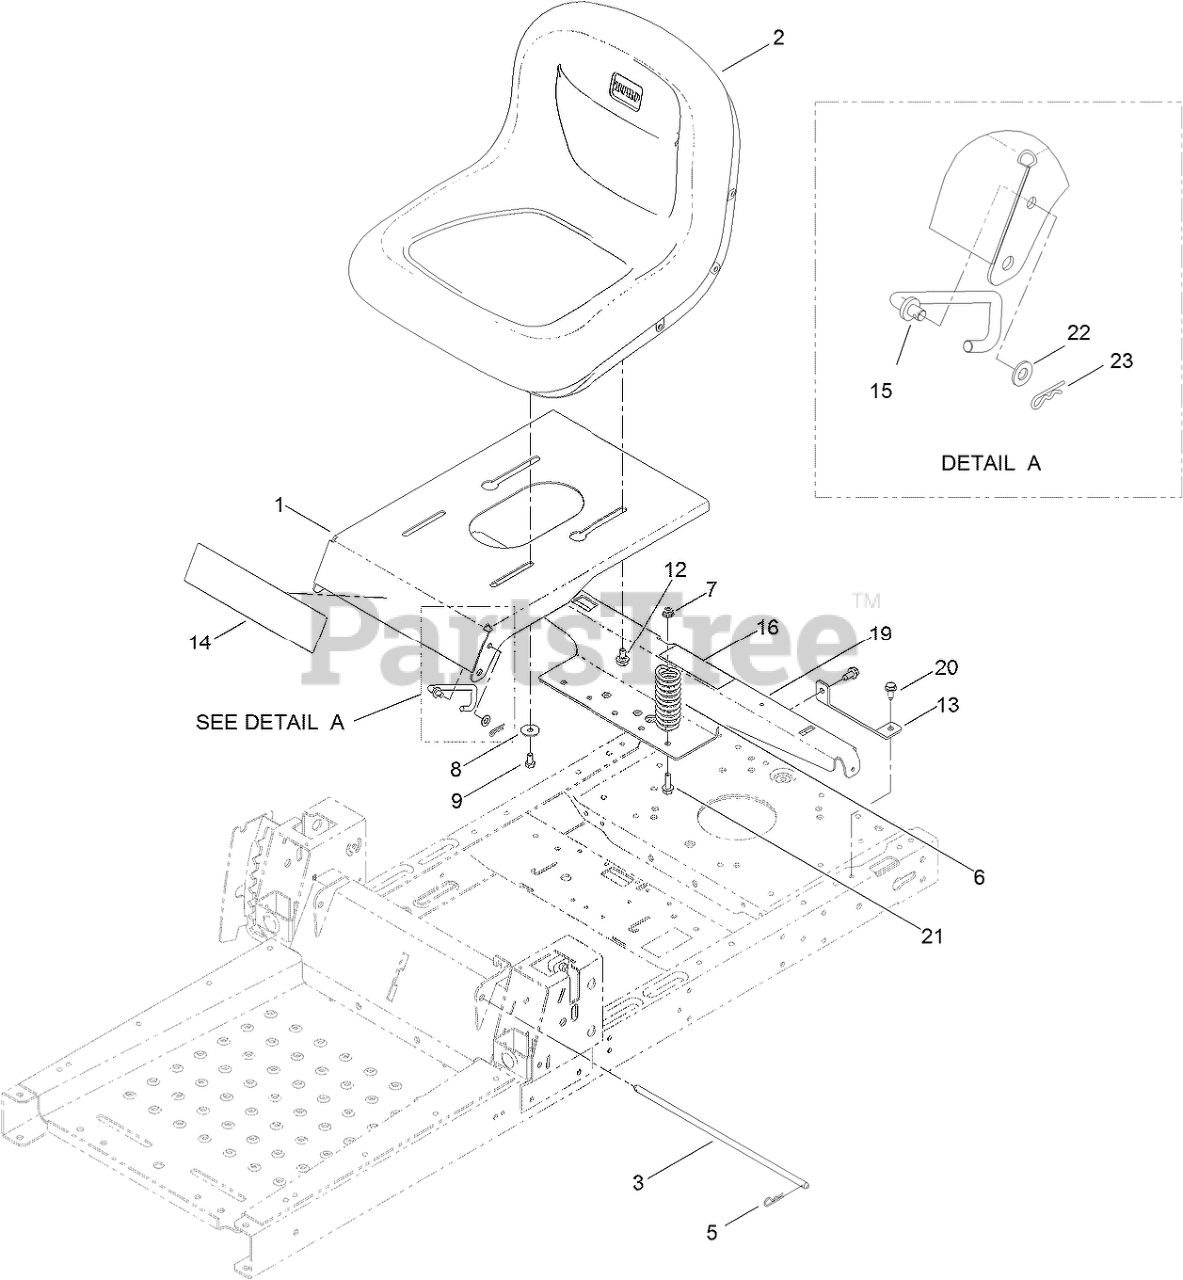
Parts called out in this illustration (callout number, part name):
1	PAN-SEAT
2	SEAT-15 INCH
3	ROD-PIVOT, NARROW
5	PIN-COTTER
6	SPRING-COMPRESSION
7	NUT-HF, NI
8	WASHER-PIVOT
9	SCREW-HH
12	BOLT-SHOULDER
13	SUPPORT-TANK, REAR
14	DECAL-TIMECUTTER
15	STOP-SEAT
16	DECAL-SERVICE, CE
19	SUPPORT-POD
20	SCREW-HWHTF
21	SCREW-HHF
22	WASHER-PLAIN
23	PIN-COTTER
